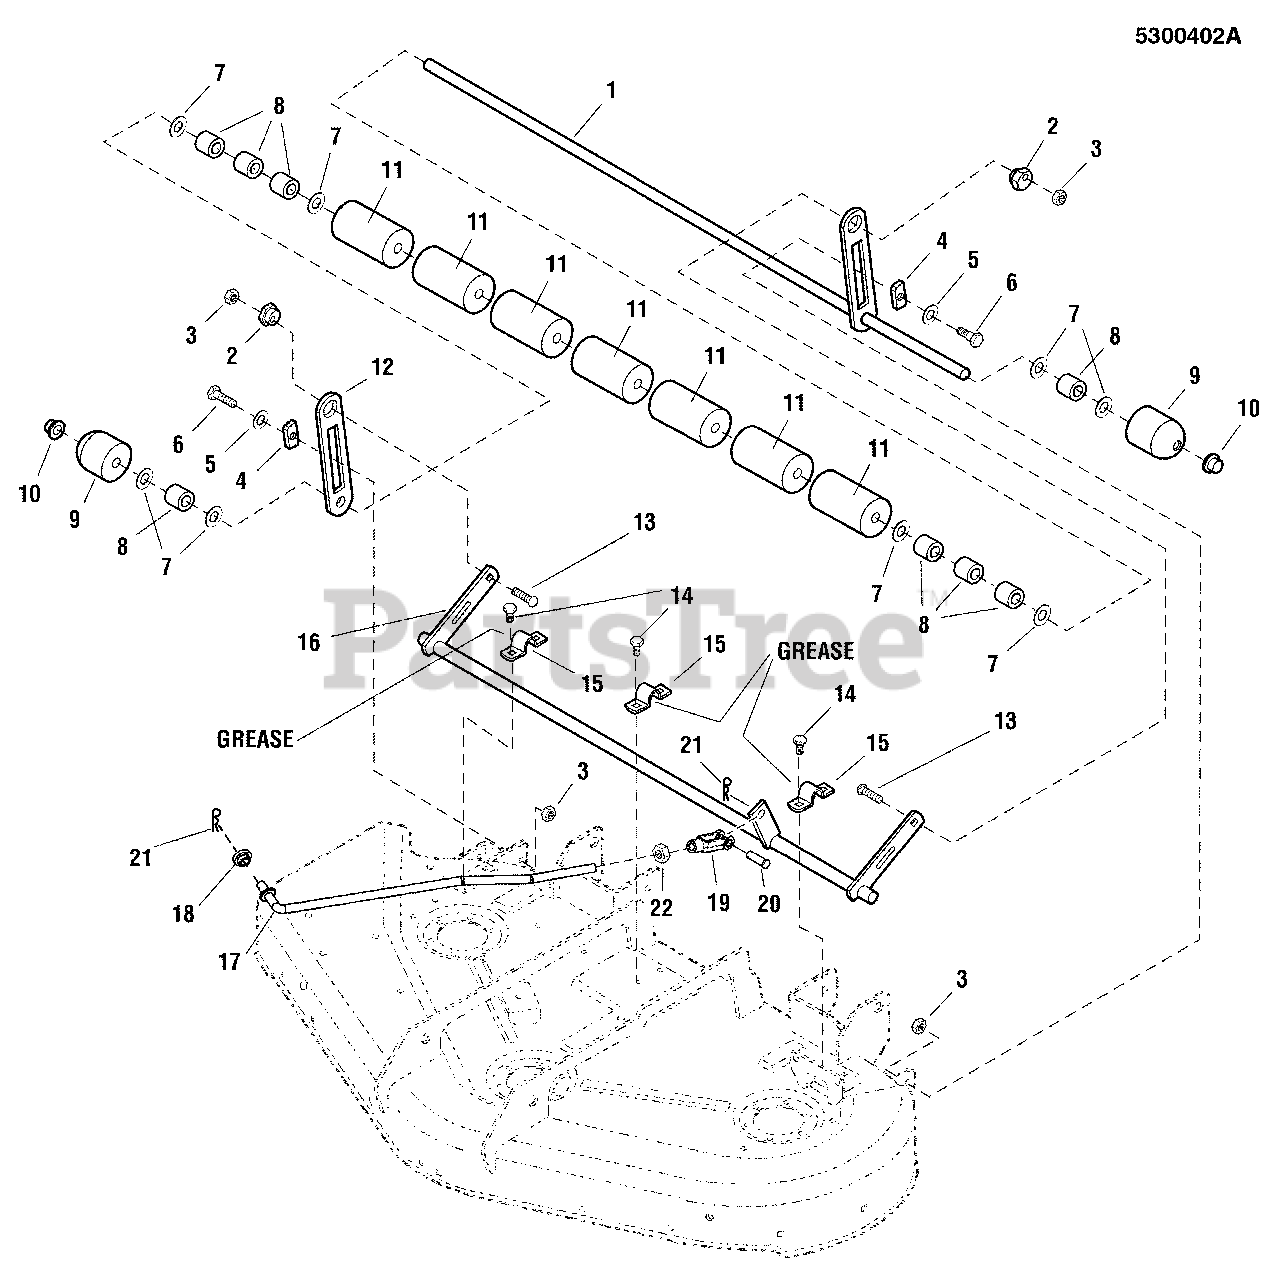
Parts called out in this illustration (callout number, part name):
1	WELD,SHAFT,ROLLER,44
2	NUT, Hex Adjusting, .99 DIA .687
3	NUT, HEX TOP LOCK SPIRAL FLNG, 3/8-16 YEL
4	SLIDE .803 X 1.7
5	WASHER-0500(0.53IDX1.25X.08THK)BLK
6	BOLT, Shoulder, 3/8-16 X 1.34
7	WASHER, 5/8
8	SPACER, .66 ID
9	ROLLER,ROUNDED
10	NUT-PUSH FOR .625 DIA STUD CAPPED BLK
12	BAR, ROLLER
13	BOLT-RD HD SH SQ NK 3/8-16X1.500 G5 BLK
14	CAPSCREW, HEX HEAD TAPTITE, 5/16-18 X 3/4
15	STRAP-1.00WD 3.06LG .134THK ROLLER ECOAT
16	WELD,SHAFT,DECK LIFT,44
17	ROD, DECK LIFT LINKAGE
18	BUSHING, DECK SUPPORT
19	CLEVIS, 1/2-20, STEEL
20	PIN, CLEVIS, 1/2 X 1 1/2, YZP
21	PIN, HAIR, .0915 X 1-7/8
22	NUT, 1/2-20 HEX JAM
